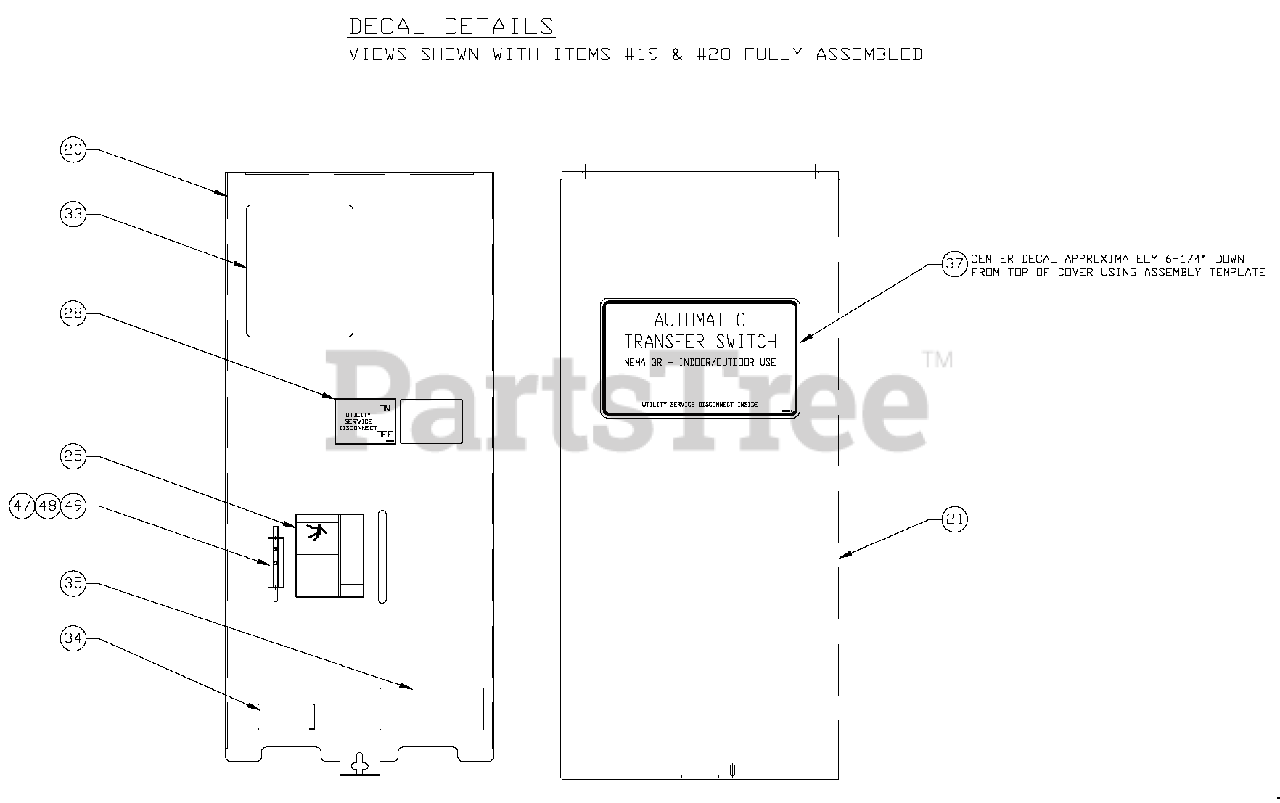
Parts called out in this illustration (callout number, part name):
20	COVER, INSIDE 200A DUAL BREAKER
21	COVER, TRANSFER SWITCH
22	CB RISER BRACKET 200A GENERAC
33	DECAL, TEST SEQUENCE
34	DECAL LIVE CIRCUIT ENG/FRN/SPN
35	DECAL, TERMINAL SHOCK HZD BI
37	DECAL FRNT CVR ATS 3R SER DIS
47	BRACKET, ARM EXTENDER
48	RIVET POP .156 X .362 AL
49	ARM EXTENDER PIN
